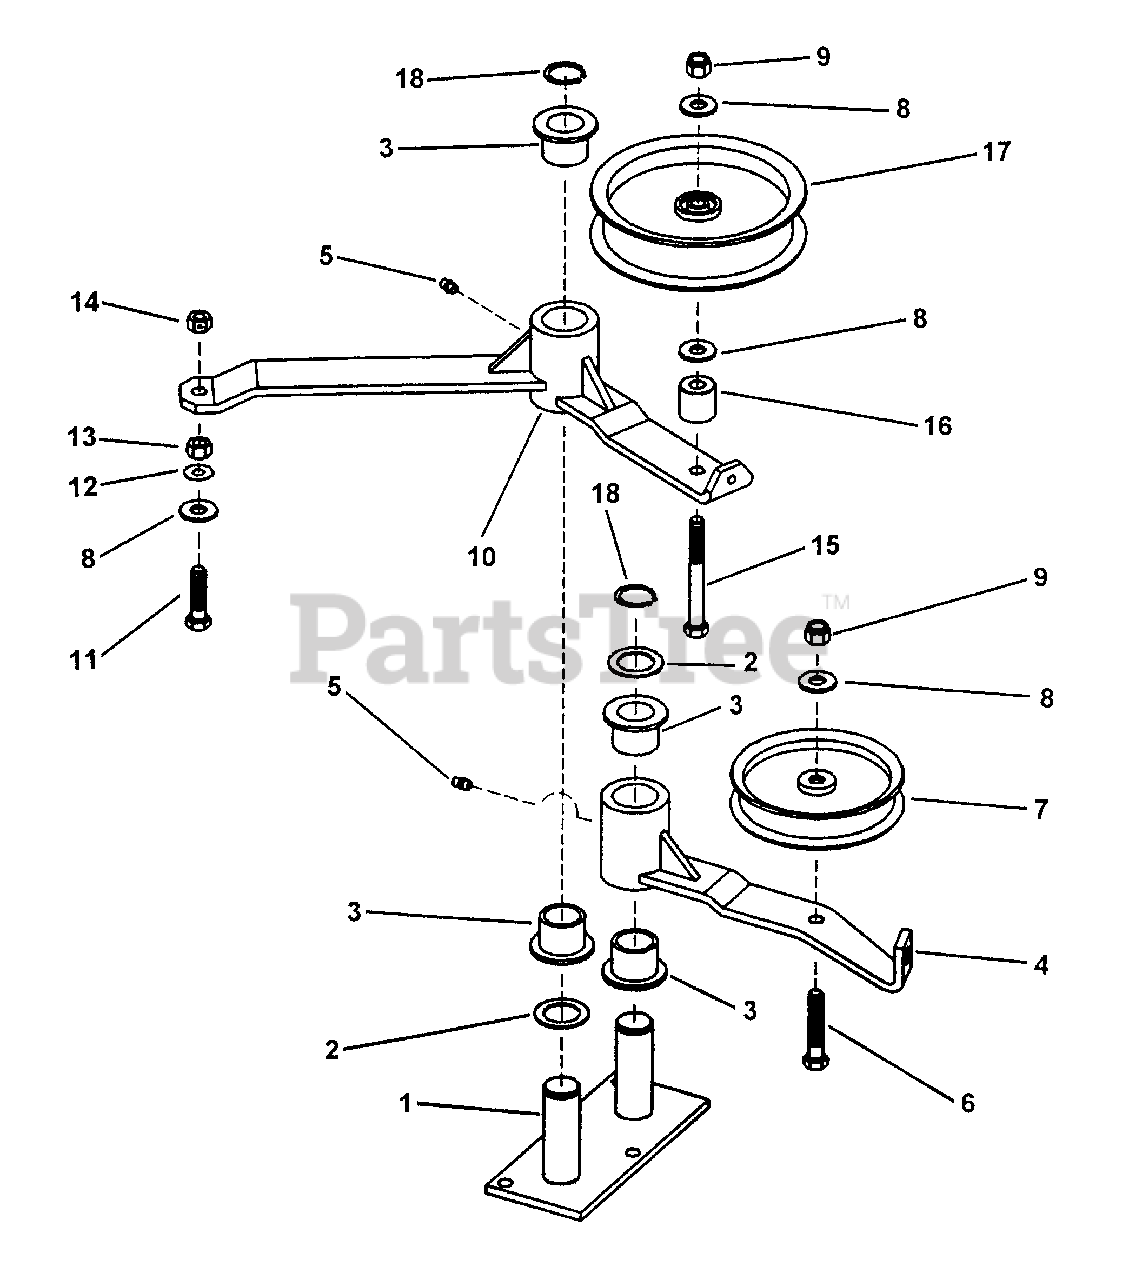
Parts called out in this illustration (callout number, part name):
1	PIVOT, Idler
2	BUSHING
3	BUSHING, Caster
4	IDLER ARM
5	FITTING, Lube
6	BOLT, 3/8-16 X 2, GD5, CZ
7	PULLEY, Idler
8	WASHER, 3/8" USS
9	NUT, 3/8-16 HEX NYLON LOCK
10	IDLER ARM, SPA520
11	SCREW, 3/8-16 x 1-1/2" Hex Head Cap, Grade 5
12	RETAINER, 3/8" Bolt
13	NUT, 3/8-16 Hex, Grade 5
14	NUT, 3/8-16 Hex Center Lock, Grade 5
15	SCREW, 3/8-16 x 3-1/4" Hex Head Cap, Grade 5
16	SPACER, Idler Pulley
17	PULLEY, Idler
18	RING, 1" Retaining
